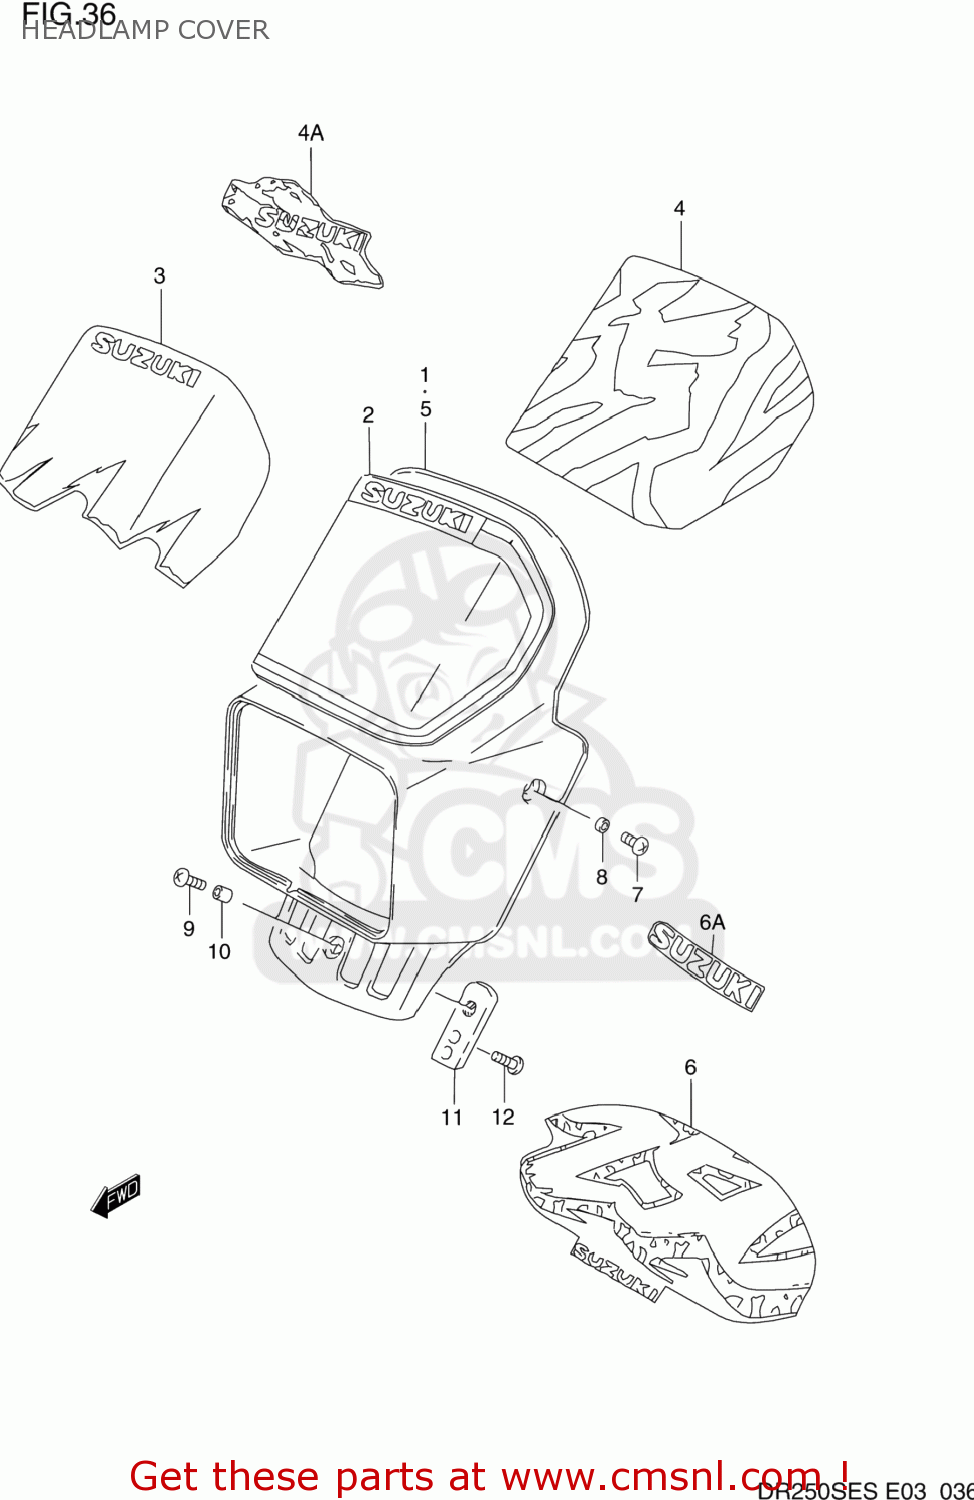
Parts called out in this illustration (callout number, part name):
1	COVER,HEADLAMP
2	TAPE,HEADLAMP COVER
3	TAPE,HEADLAMP COVER
4	TAPE,HEADLAMP COVER
4A	TAPE,HEADLAMP COVER
5	HOUSING ASSEMBLY,HEADLAMP
6	EMBLEM,HEADLAMP COVER
6A	EMBLEM,HEADLAMP COVER
7	SCREW 6X12
8	SPACER (6.1X8X3.5)
9	SCREW
10	SPACER (6.1X8X12)
11	PLATE,HEADLAMP COVER
12	SCREW
